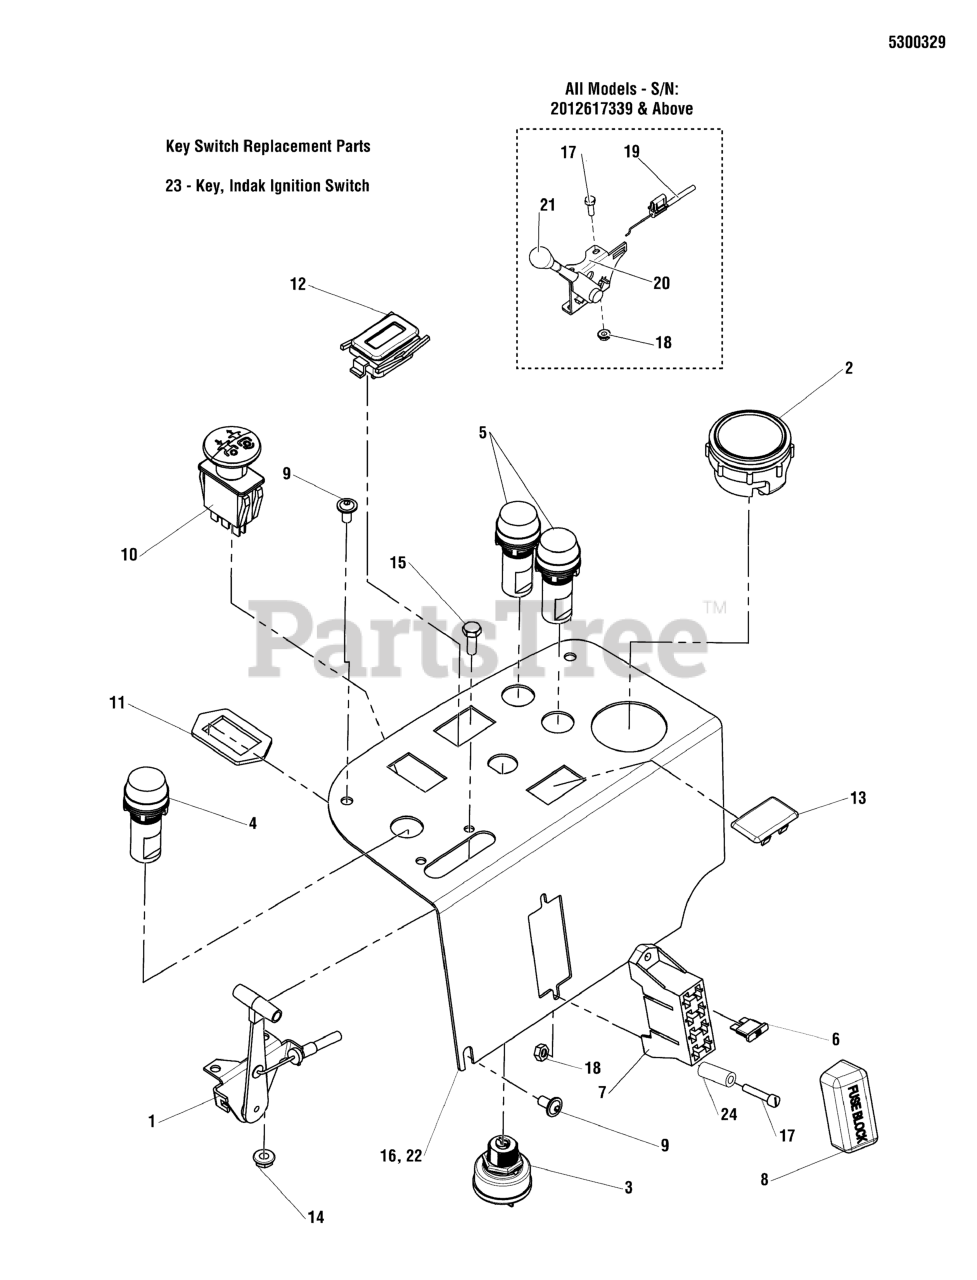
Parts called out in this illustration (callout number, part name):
1	CABLE, THROTTLE CONTROL, 47"
2	GAUGE, WATER TEMPERATURE
3	SWITCH, IGNITION, YANMAR
4	LIGHT, GLOW PLUG, 22MM AMBER
5	LIGHT, WARNING, 22MM RED
6	FUSE, ATO, 20 AMP
7	FUSE, BLOCK
8	COVER, VINYL FUSE BLOCK
9	SCREW, 1/4-20 X 1/2" ALLEN BH
10	SWITCH, BLADE ENGAGEMENT
11	RING, SWITCH RETAINER
12	HOUR METER
13	PLUG, .820X1.44 HOLE, BLACK PLASTIC
14	NUT, 1/4-20 HEX NYLOCK FLANGE
15	BOLT, 1/4-20 X 3/4" GD5 YZ
16	PLATE, CONTROL PANEL, DIESEL -IS2000 BLK
17	SCREW, #10-24 X 3/4" ROUND PHILLIPS
18	NUT, #10-24 HEX NYLON LOCK
19	CABLE, THROTTLE 47"
20	LEVER, THROTTLE CONTROL, HEAVY-DUTY
21	THROTTLE CONTROL HANDLE/KNOB
22	PLATE, CONTROL PANEL, DIESEL -IS2000 BLK
23	KEY, INDAK IGNITION SWITCH
24	SPACER, .20 X .38 X 1.25
